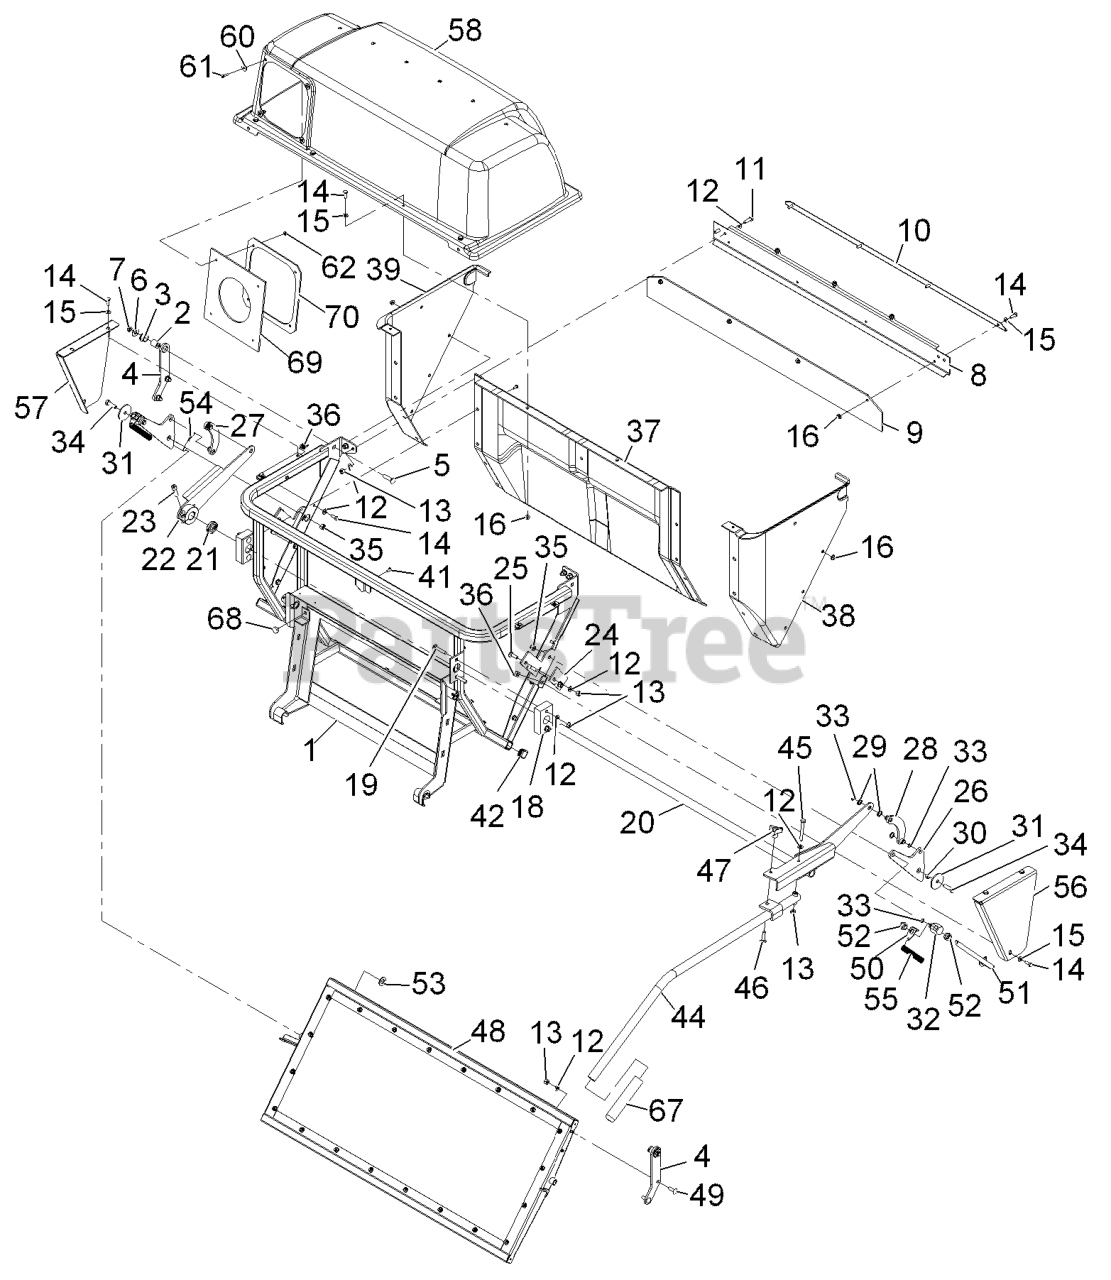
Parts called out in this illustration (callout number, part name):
1	Frame ASM
2	Pin-Pivot, Hinge
3	Bearing
4	Plate, Hinge
5	Bolt-Carriage 3/8-16 X 1 1/2
6	Washer-3/8 Std
7	Nut-Nyloc 3/8-16 Thin
8	Plate-Rear
9	Seal-Door
10	Strap-Hold Down
11	Screw-HH 5/16-18 X 1
12	Washer-5/16 SAE
13	Nut-Nyloc 5/16-18
14	Screw-HH 1/4-20 X 3/4
15	Washer-1/4 SAE
16	Nut-Whizlock 1/4-20
18	Bearing
19	Bolt-Carriage 5/16-18 X 1 3/4
20	Bellcrank
21	Shaft-Collar
22	Link
23	Screw-Sh 3/8-16 X 1 1/4
24	Stop-Linkage
25	Bolt-Carriage 5/16-18 X 1
26	Arm-Linkage, Door
27	Link-RH
28	Link-LH
29	Washer-Nylon
30	Bearing-Linkage, Pivot
32	Trunnion-Link
33	Ring-Retaining
34	Screw-HH 3/8-16 X 1 1/4
35	Nut-Nyloc 3/8-16
36	Nut-Retainer-Panel 1/4-20
37	Panel-Bagger
38	Panel-Bagger, LH
39	Panel-Bagger, RH
44	Handle-Qd7
45	Screw-HH 5/16-18 X 2 1/2
46	Bolt-Carriage 5/16-18 X 1 1/4
47	Knob-3 Prong
48	Asm, Door
49	Bolt-Carriage 5/16-18 X 1 Sp
50	Anchor-Spring
51	Link-Door
52	Nut-Hex 1/2-20
53	Washer-1/2 SAE
54	Hairpin-Cotter
58	Asm, Hood
61	Screw-PPH #10-24 X 7/8
62	Nut-Nyloc #10-24
67	Handle-Grip
69	Seal-Chute
70	Clamp-Seal
